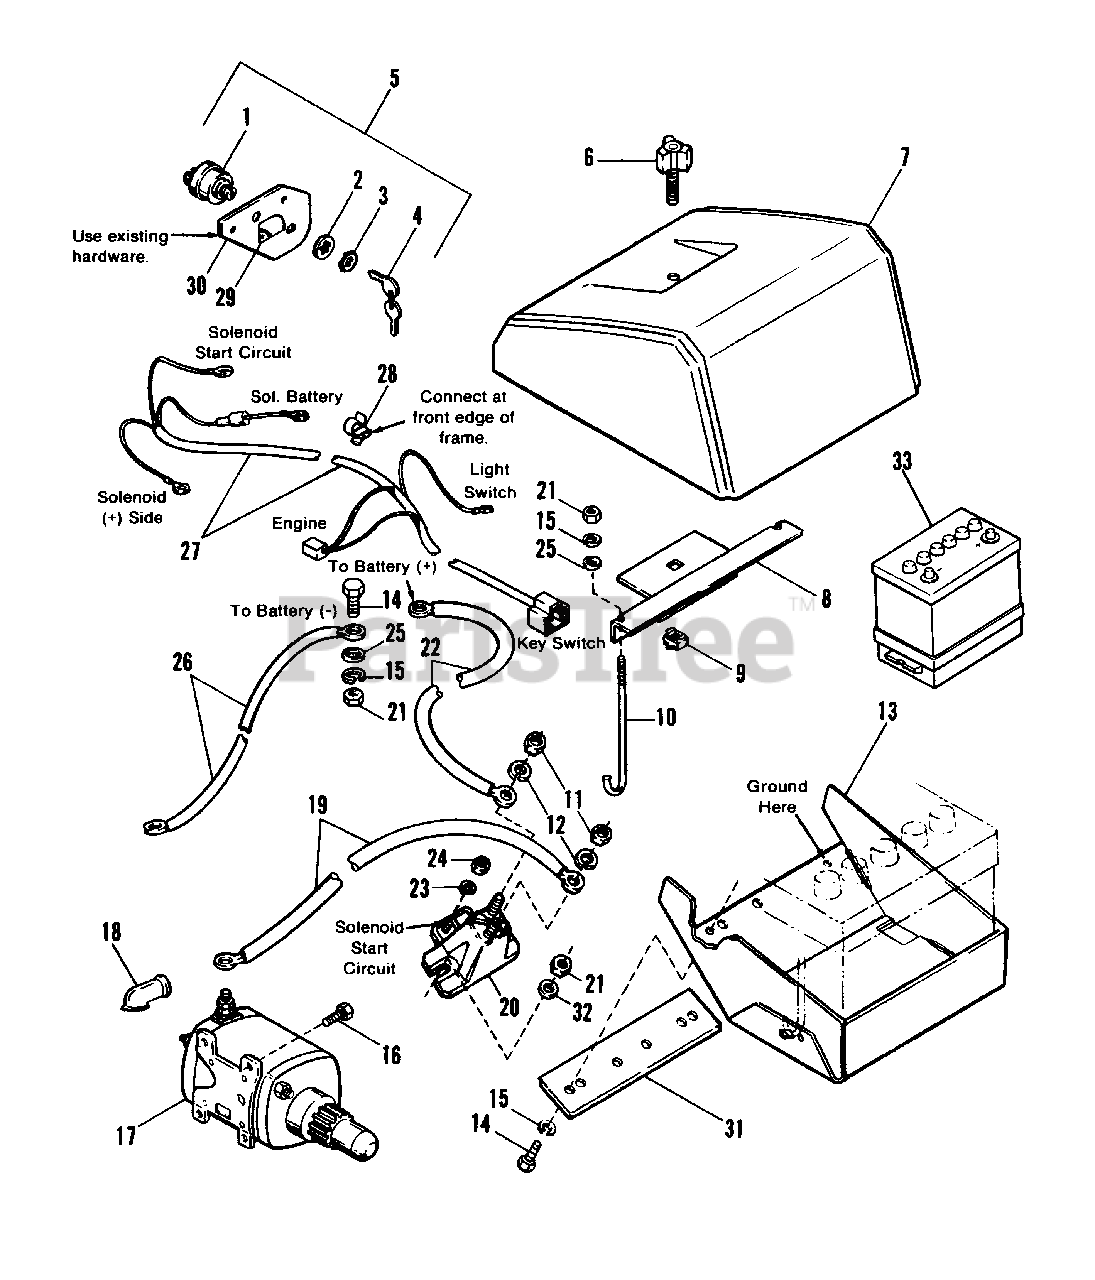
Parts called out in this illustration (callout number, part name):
1	TUBE (Service Only) 4.80/4.00-8
2	LOCKWASHER, Int. Tooth, 5/8
2	TIRE, (4.80/4.00-8)
3	NUT, Special
3	VALVE STEM & CAP
4	KEY, Set of Two
4	WHEEL & HUB ASSY.
5	SWITCH, Key (Incl. Ref. Nos. 1, 2, 3 & 4)
5	PIN
6	CLIP, Hair Pin
7	WHEEL & TIRE ASSY.
8	HOLD DOWN ASSY., Battery
9	NUT, Cage, Tinnerman, 5/16-18
11	NUT, Hex, Full, 5/16-18
12	LOCKWASHER, 5/16
13	SUPPORT ASSY., Battery
14	CAPSCREW, Hex, 1/4-20 x 3/4
15	LOCKWASHER, 1/4
16	SCREW
17	MOTOR, Starter (not serviced)
18	COVER, Terminal
19	WIRE, Solenoid to Starter
20	SOLENOID
21	NUT, Hex, Full, 1/4-20
22	WIRE, Battery to Solenoid
23	LOCKWASHER, #10
24	NUT, Hex, Full, #10-32
25	WASHER, Flat, 1/4
26	CABLE, Battery to Ground
27	HARNESS, Wiring
29	DECAL, Key Switch
30	BRACKET, Key Switch
31	PLATE, Reinforcement
32	WASHER, 1/4
33	BATTERY (Not included in kit)
